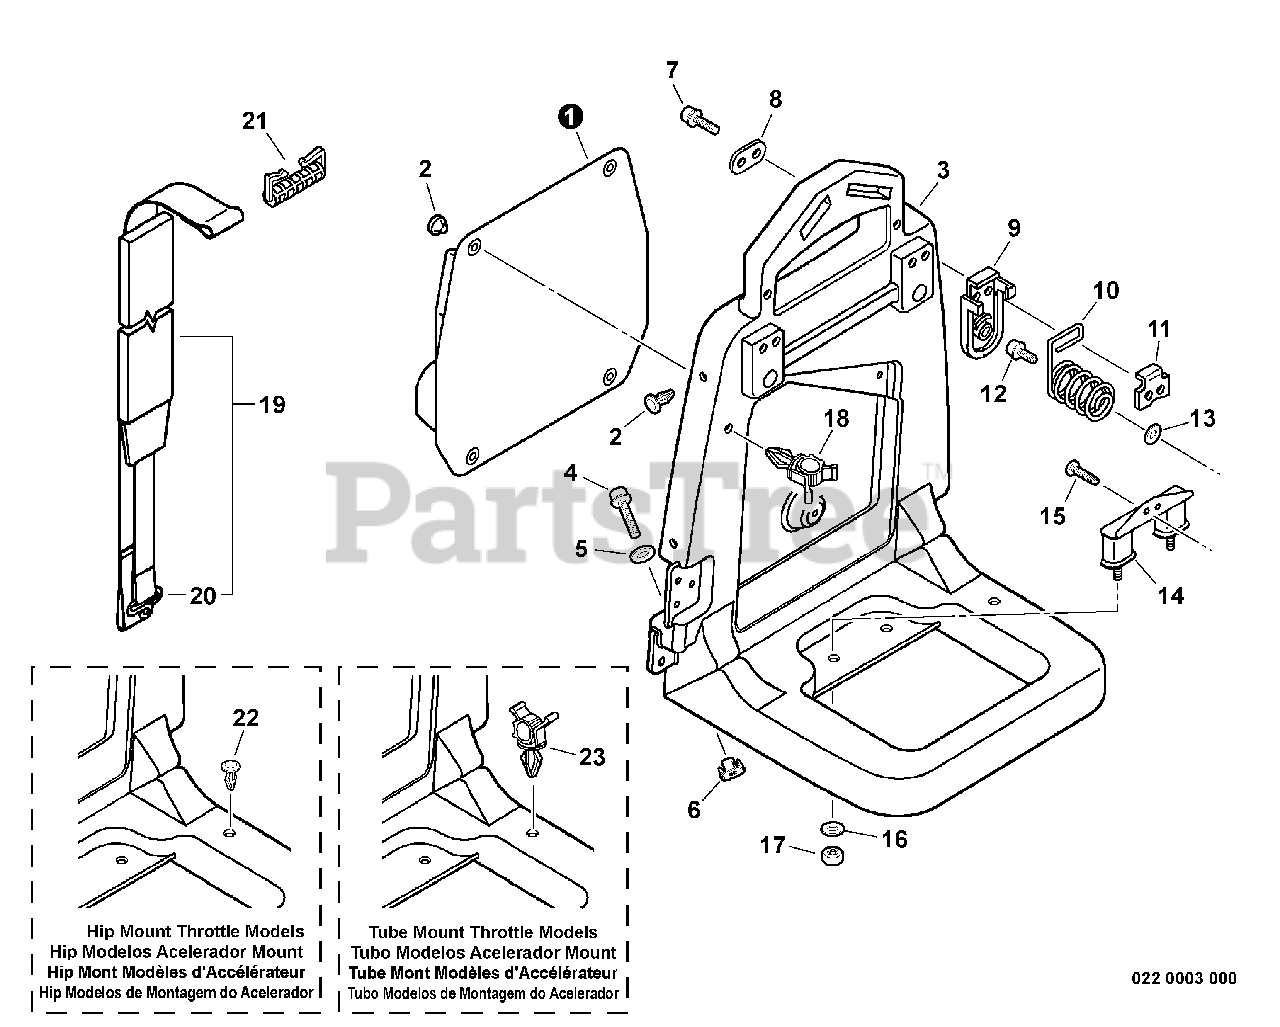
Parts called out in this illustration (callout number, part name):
1	CUSHION, BACKPACK
3	FRAME, BACKPACK
4	SCREW - 6X25
5	WASHER - 6
7	SCREW - 5X20
9	BRACKET, SPRING
11	RETAINER
12	SCREW - 5X20
13	WASHER - 5
14	CUSHION
15	SCREW - 5X16 -- TAPPING
17	NUT - 5 -- FLANGE
18	CLIP, CABLE
19	BACKPACK STRAP ASSY
21	RETAINER, HARNESS
23	CLIP, CABLE
